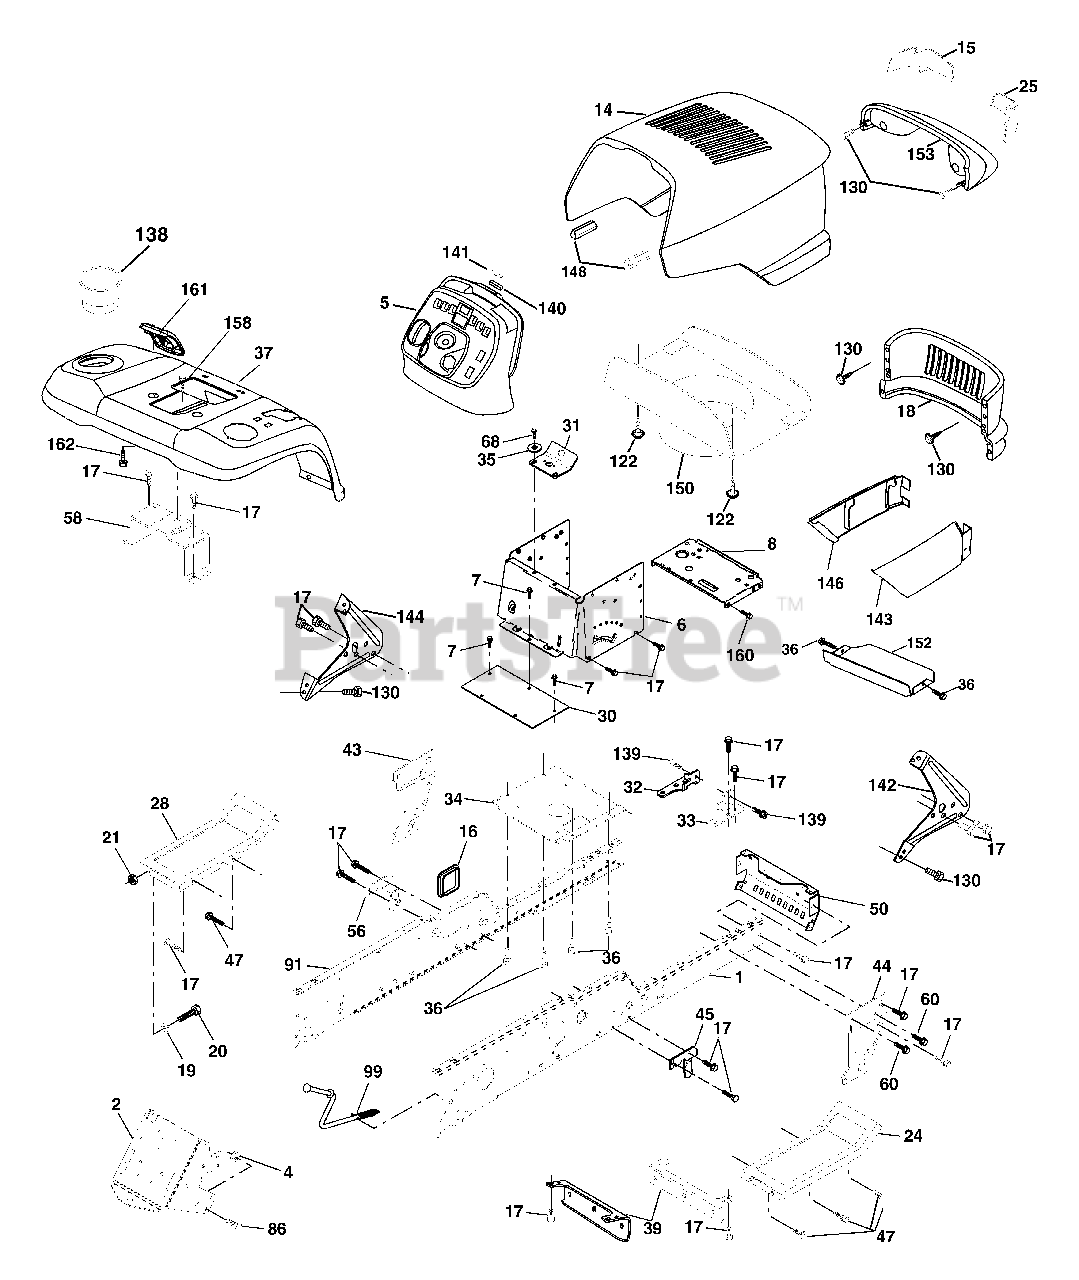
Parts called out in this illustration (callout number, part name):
1	Rail, Frame RH
2	Drawbar, Gt
4	Nut, Lock Hex 7/16-14 Unc
5	Dash, Plastic
6	Dash, 1PCS, Lower
7	Screw, Thd Cut 1/4-20 x 1/2
8	Support, Battery
14	Hood Asm., Pnt
15	Lens RH
16	Cover, Access
17	Screw, 3/8-16 x 3/4
18	Grille
19	Washer 13/32 x 13/16 x 12 Ga.
20	Bolt, Fin Hex 3/8-16 x 1
21	Nut, Crownlock 3/8-16
24	Footrest, RH
25	Lens LH
28	Footrest, LH
31	Bracket Supt 1-pc Vgt Steering
32	Bracket, Frame Pivot Lh
33	Bracket, Frame Pivot Rh
34	Plate Asm Engine Chassis
35	Washer 11/32 x 11/16 x 16 Ga.
36	Screw 5/16-18 x 3/4
37	Fender, Pnt.
39	Bracket, Axle Front
43	Bracket, Spnsn Front Lh
44	Bracket, Spnsn Front Rh
45	Bracket Asm., Susp Chassis Rh
47	Screw Thdrol 3/8-16 x 1/2
50	Bracket, Chassis Front
56	Bracket Asm., Susp Chassis Lh
58	Bracket Asm., Fender
60	Screw 3/8-16 x 1-1/4
68	Screw, 5/16-18 x 1/2
86	Bolt, Fin Hex 7/16-14 Unc
91	Rail, Frame Lh
99	Rod Asm. Bypass
122	Screw Hex WSHD 8-18 x 7/8
130	Screw Hw Hd Hi-Lo #13-16 x 3/4
138	Cupholder
139	Bolt Shoulder 5/16-18
140	Magnet Stealth
141	Striker Plate
142	Bracket Dash Stealth RH
143	Skirt Grille RH
144	Bracket Dash Stealth LH
146	Skirt Grille LH
148	Extrusion Bumper
150	Duct Heat Hood
152	Shield, Browning
153	Lens, Headlight Bar
158	Screw 3/8-16 x 1/2
160	Screw 5/16-18 x 1/2
161	Cosole Fuel Window
162	Screw 1/4-1/2 Unc
